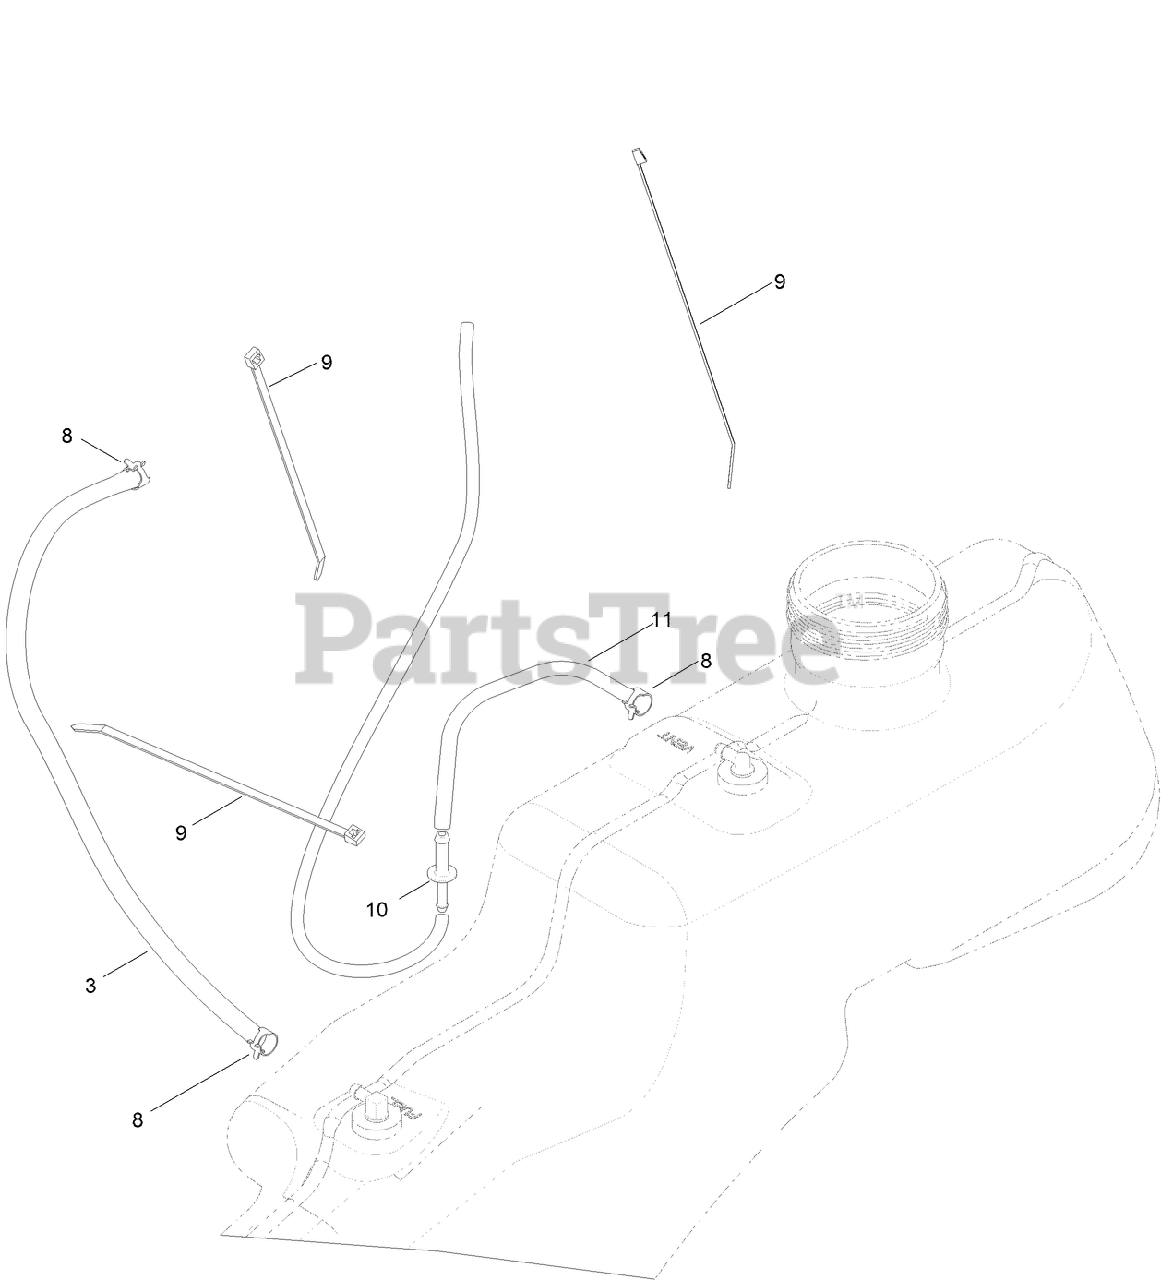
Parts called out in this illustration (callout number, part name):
3	HOSE-FUEL
8	CLAMP-HOSE
9	TIE-CABLE
10	ADAPTOR-ORIFICE
11	HOSE-FUEL
